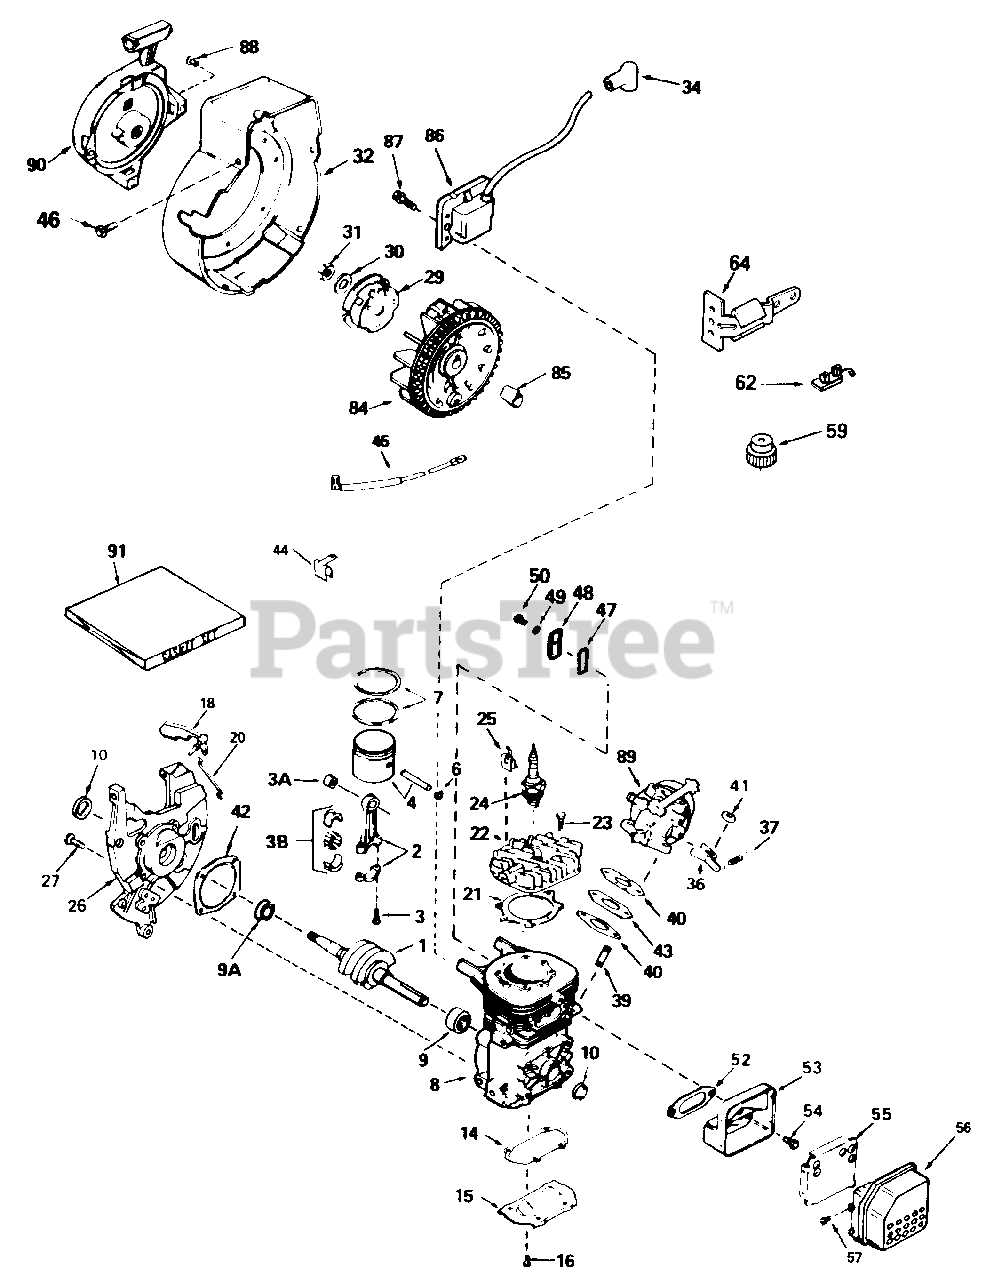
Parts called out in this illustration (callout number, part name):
1	Crankshaft
2	Rod Ass'y., Connecting
3	Screw, Connecting Rod
3A	Bearing, Cartridge
3B	Bearing & Liner Set, Needle (37 Needles)
4	Piston and Pin Ass'y.
6	Ring, Piston Pin Retaining
7	Ring Set, Piston
8	Block Ass'y., Cylinder
9	Bearing, Needle
9A	Bearing, Ball
10	Seal, Crankshaft
14	Gasket, Cover
15	Plate, Cover
16	Screw, Pan Flex Hd., 10-24 x 1/2
18	Vane Ass'y., Air
20	Link, Governor
21	Gasket, Cylinder Head
22	Head, Cylinder
23	Screw, Pan Flex Hd., 1/4-20 x 3/4
24	Plug, Spark
26	Base Ass'y., Blower Housing
27	Screw, Torx Pan Hd., 1/4-20 x 5/8
29	Cup, Starter
30	Washer, Spring
31	Nut, Flywheel
32	Housing, Blower
34	Cover, Spark Plug
36	Lever, Adjusting
37	Spring, Adjusting Lever
39	Stud, Carburetor
40	Gasket, Carburetor
41	Nut, Hex, 1/4-28
42	Gasket, Housing Base
43	Spacer, Carburetor
44	Clip, Spring
45	Wire, Ground
46	Screw, Hex Washer Hd. Powerlok Thread, 1/4-20 x 3/8
47	Gasket, Cover
48	Cover Ass'y., Compression Release
49	Washer, Flat No. 10
50	Screw, Pan Flex Hd., 10-24 x 1/2
52	Gasket, Muffler
53	Base, Muffler
54	Screw, Hex Washer Hd., 1/4-20 x 5/8
55	Baffle, Muffler
56	Cap, Muffler
57	Screw, Hex Hd. Self-Tap, 8-18 x 3/8
59	Cap Ass'y., Fuel
62	Terminal Ass'y.
64	Bracket, Key Switch
85	Sleeve, Flywheel
86	Solid State Ass'y.
87	Screw, Hex Hd. Sems, 10-24 x 1
88	Rivet, Pop (3116" Dia.)--Purchase Locally
89	Carburetor
90	Starter Ass'y., Rewind
91	Gasket Set
